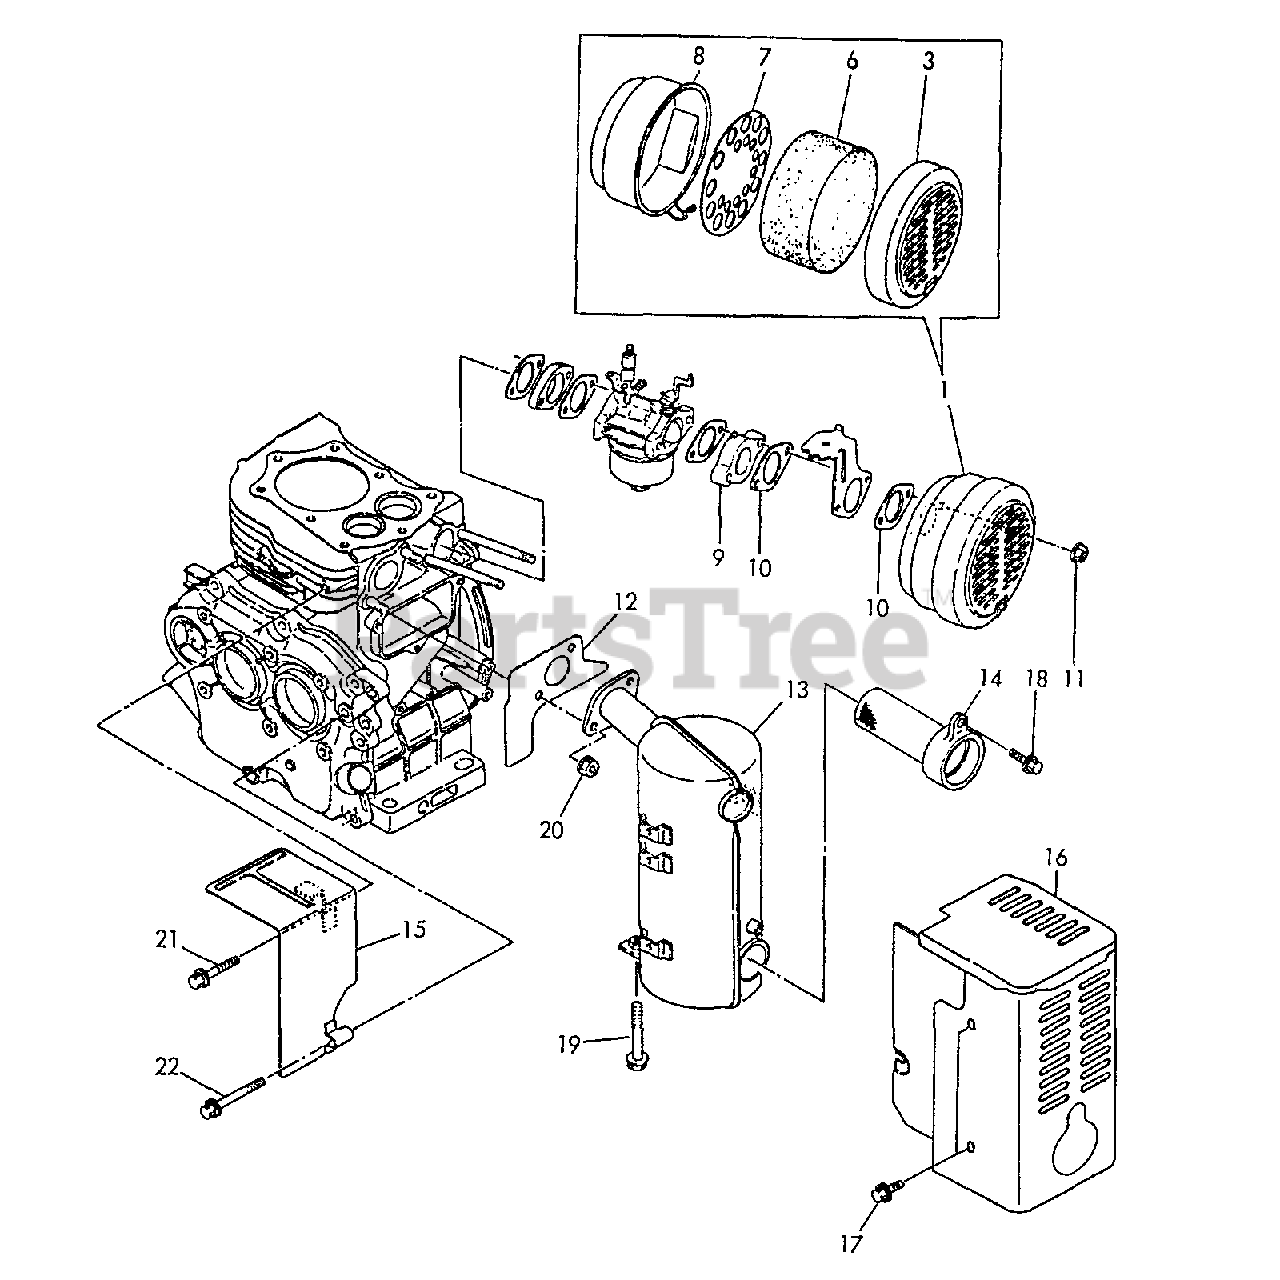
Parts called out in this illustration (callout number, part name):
1	AIR CLEANER ASSY
3	CASE, AIR FILTER
6	FILTER, AIR
7	HOLDER, ELEMENT
8	COVER, AIR FILTER
9	SPACER
10	GASKET, INTAKE
11	NUT - 6 -- FLANGE
12	GASKET, EXHAUST
13	MUFFLER
14	SCREEN, SPARK ARRESTOR
15	PLATE, GUIDE
16	COVER, MUFFLER
17	BOLT - 6X8 -- PLATED
18	BOLT - 6X10 -- PLATED
19	BOLT - 8X30 -- PLATED
20	NUT - 8
21	BOLT - 6X8 -- PLATED
22	BOLT - 6X30
